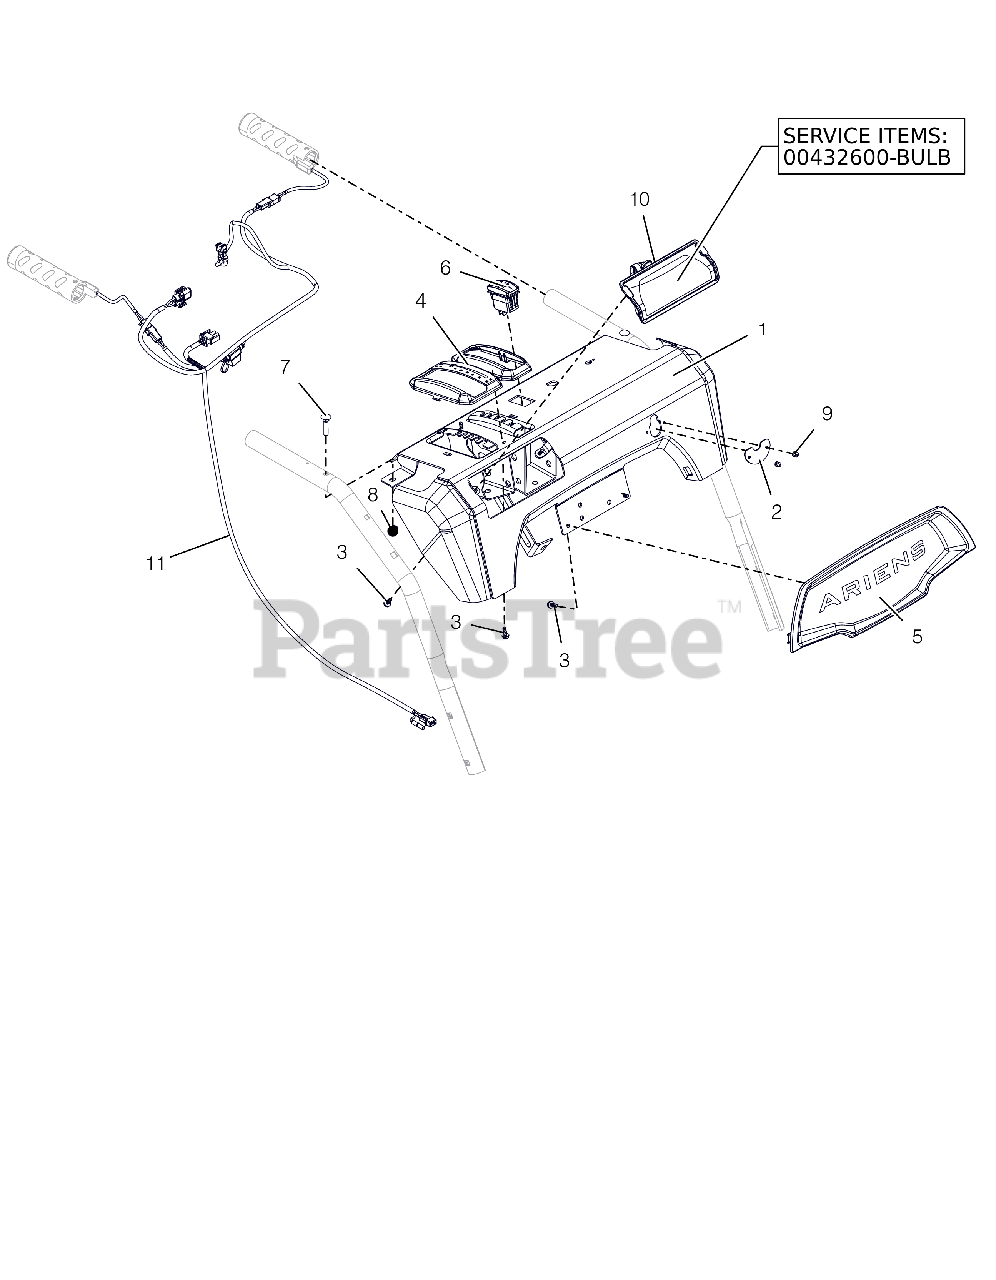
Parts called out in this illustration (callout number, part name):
1	PANEL, CONTROL-EFI ID W/DECAL
2	COVER, DASH BRKT, ID
3	SCR-TAP #10X.50 BOSS INDHXHD
4	BEZEL, SHIFT - FRICTION SNOW
5	BEZEL, DASH - ARIENS LG DASH
6	SWITCH,ROCKER SPST-ON/OFF
7	BLT-RDHDXLSQNK.25-20X1.25 G5ZC
8	@NUT-LK-CTR-FLG .25-20 YWZC
9	RVT-POP #43 .125X.313 STL ZINC
10	HEADLIGHT ASY, HALO 20W 2SHOT
10	BULB, LIGHT-HALOGEN 20W
11	HARNESS,LIGHT&WARMER - EFI
